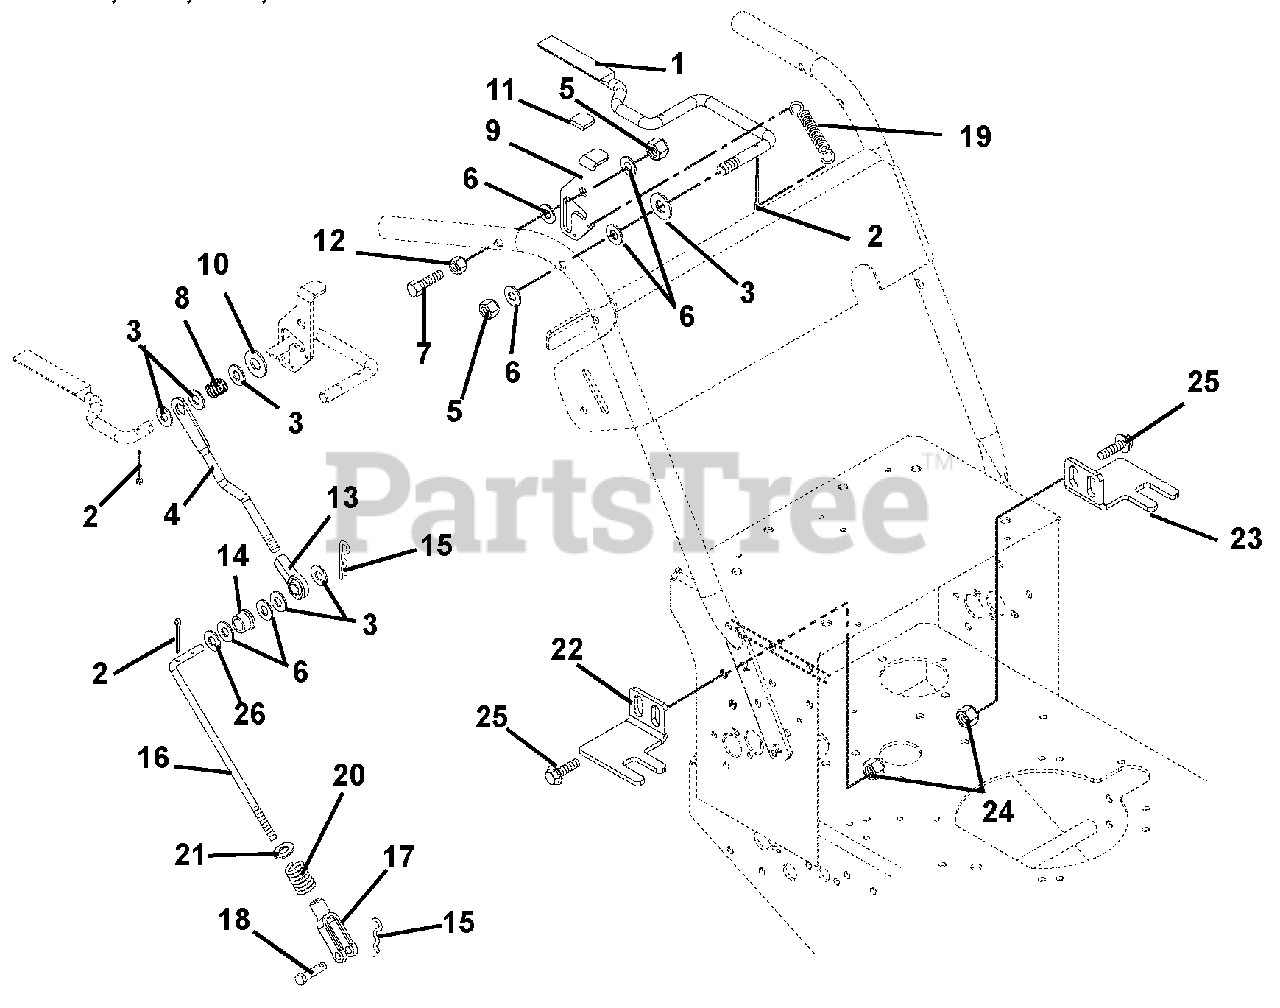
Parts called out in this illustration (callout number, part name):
1	Lever, Hand Control Left Hand
2	Pin-Cotter .09 x .75
3	Washer-Flat-Steel .406 x .812 x .065
4	Rod, Steering Link
5	Nut-Locking-Center .38-16
6	Washer-Flat-Nylon .375 x .75 x .060
7	Bolt-Hex .38-16 x 2.50 Grade 2
8	Spring-Compression .045 x .60 x .75
9	Latch, Right Hand Thumb
10	Washer-Flat-Steel .50 x 1.25 x .083
11	Grip, Thumb Latch
12	Nut-Locking-Jam-Center .375-16
13	Rod End, .38
14	Bushing-Flange .375 x .469 x .25
15	Pin-Hair Internal .08 x .18 x 1.18
16	Rod, Speed Control
17	Clevis, .38-24 Adjustable
18	Pin-Clevis .38 x 1.25
19	Spring-Tension .041 x .50 x 1.75
20	Spring-Compression .093 x .59 x 1.50
21	Washer-Flat-Steel .438 x 1.00 x .083
22	Stop, Hydro Neutral Right Hand
23	Stop, Hydro Neutral Left Hand
24	Nut-Locking-Top-Flange .25-20
25	Bolt-Serrated Hex Flange Washer Head .25-20 x .75
26	Washer-Flat-Nylon .52 x 1.00 x .08
